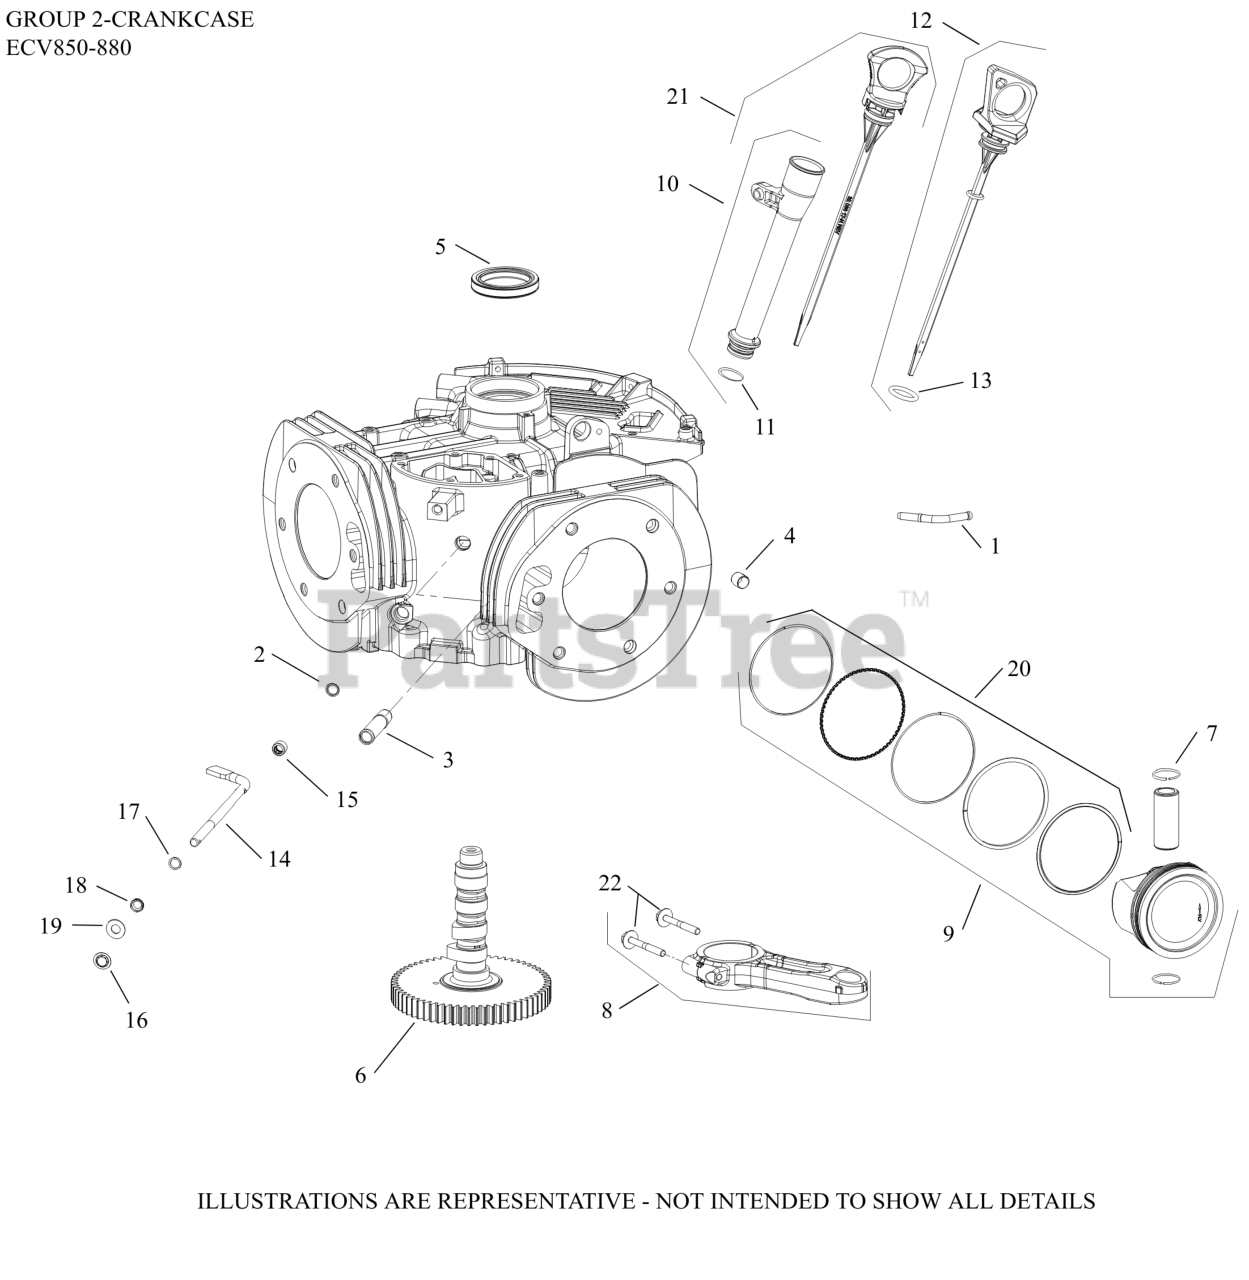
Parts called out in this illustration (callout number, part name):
3	FITTING, BREATHER HOSE
4	PIN, LOCATING
5	SEAL, OIL-(#2503218S)
6	KIT, CAMSHAFT
7	RETAINER, PISTON PIN
8	ROD, CONNECTING ASSEMBLY
9	KIT, PISTON RINGS, PIN & CLIPS (STD)
9	KIT, PISTON RINGS, PIN & CLIPS (.25)
9	KIT, PISTON RINGS, PIN & CLIPS (.50)
14	SHAFT, GOVERNOR CROSS
15	BEARING, NEEDLE
16	RETAINER, RING
17	WASHER, FLAT 11/32"
18	SEAL, OIL
19	WASHER, FLAT 9 MM
20	KIT, RING SET (STD)
21	KIT, DIPSTICK AND TUBE WITH RINGS
22	KIT, ROD BOLTS
